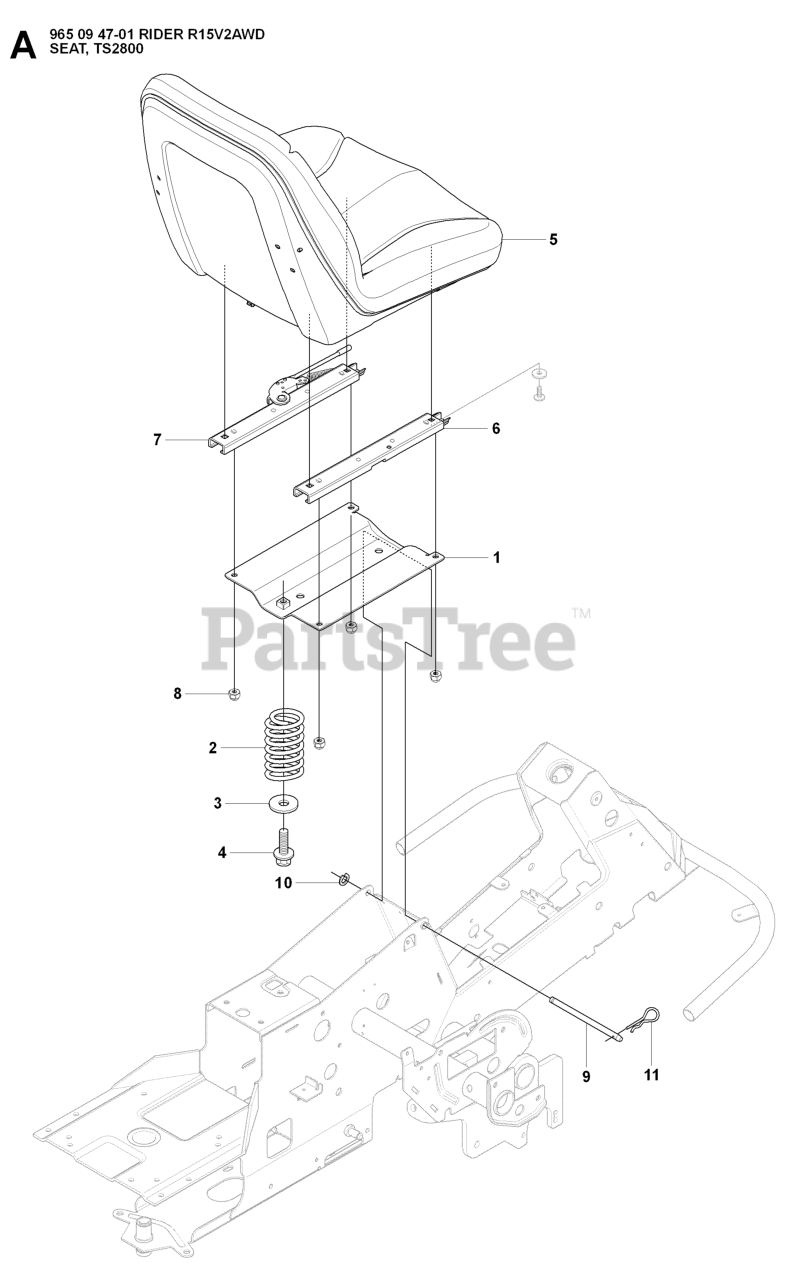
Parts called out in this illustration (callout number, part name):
2	SEAT SPRING
4	Screw M10x25
5	SEAT
8	LOCKNUT M8
10	RETAINING RING SGA 10
